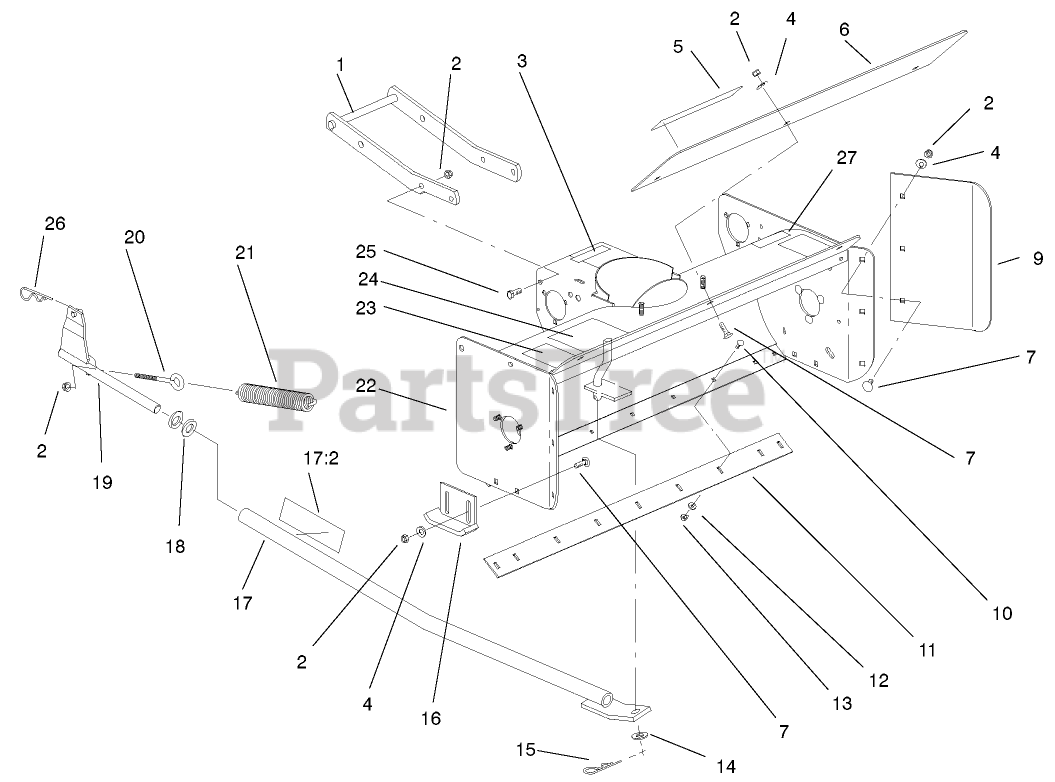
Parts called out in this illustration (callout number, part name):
1	FRAME-MOUNTING
2	NUT-LOCK, NI
4	WASHER-FLAT
6	PLATE-EXTENSION
7	BOLT-CARR
9	PLATE-EXTENSION, RH
12	WASHER-FLAT
13	NUT-LOCK, NI
14	WASHER-FLAT
15	PIN-COTTER, HAIR
17	LIFT TUBE W/DECAL ASM
17:2	DECAL - WARNING
18	WASHER-FLAT
20	EYEBOLT
21	SPRING
22	AUGER W/DECALS ASM
23	DECAL-DANGER
24	DECAL-WARNING
25	SCREW-HH
26	PIN-HAIR
27	DECAL - WARNING
